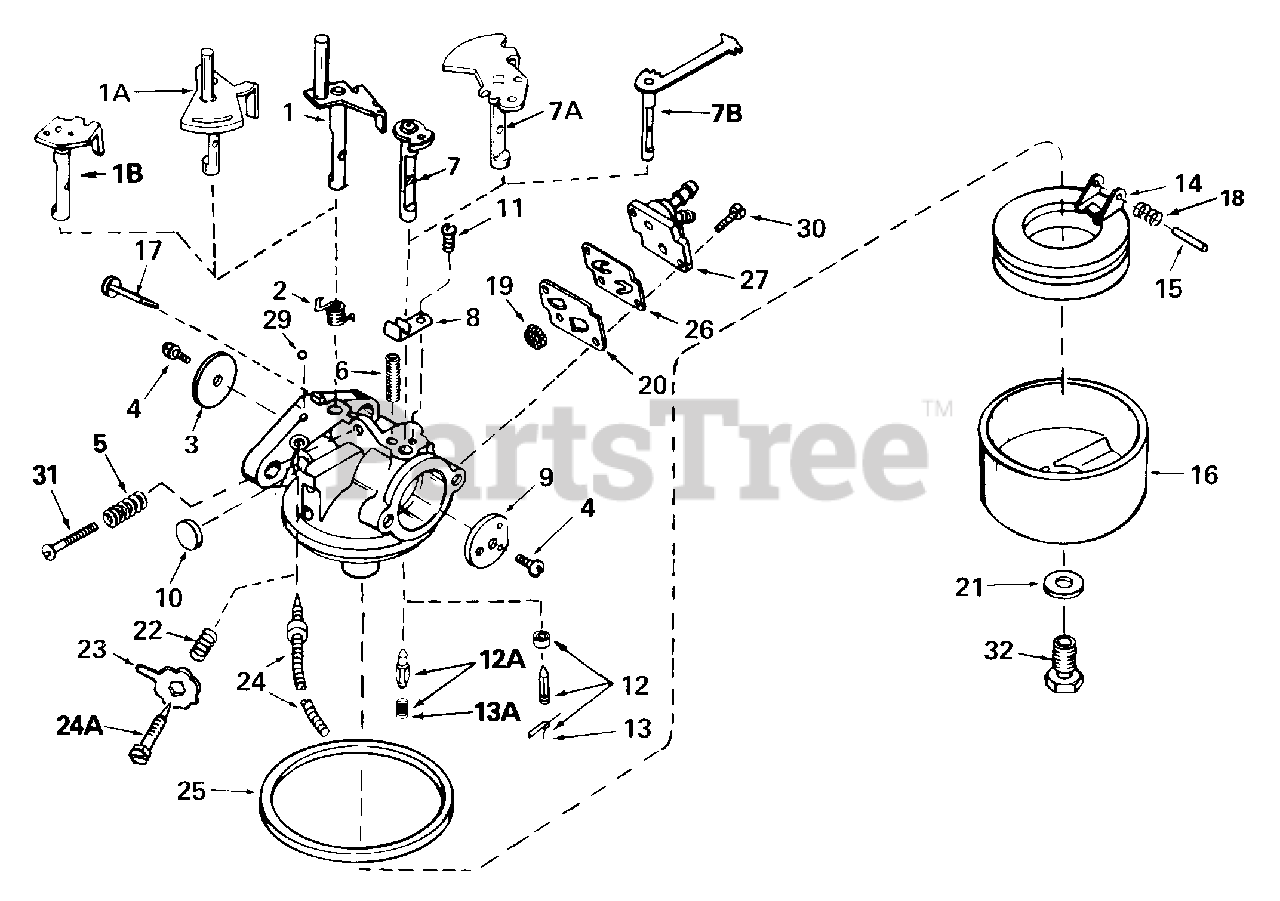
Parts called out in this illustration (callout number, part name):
1A	"Shaft & Lever Assy., Throttle
2	Spring, Throttle return
3	Shutter, Throttle
4	Screw, Throttle & Choke shutter
6	Spring, Choke positioning
7A	Shaft & Lever Assy., Choke
9	Shutter, Choke
10	Plug, Welch
12	Inlet Needle, Seat & Clip Assy.
13	Clip, Inlet needle
14	Float, Carburetor
15	Shaft, Float
16	Bowl, Float
17	Element, Pump
19	Screen, Filter
20	Gasket
21	Gasket, Bowl-to-body
22	Spring, Adj. screw
23	Knob, Adj. screw
24A	Screw, Idle adj.
25	Gasket, Bowl-to-body
26	Valve, Flap
27	Cover Assy., Valve
29	Shot, Lead
32	Nut, Float bowl
